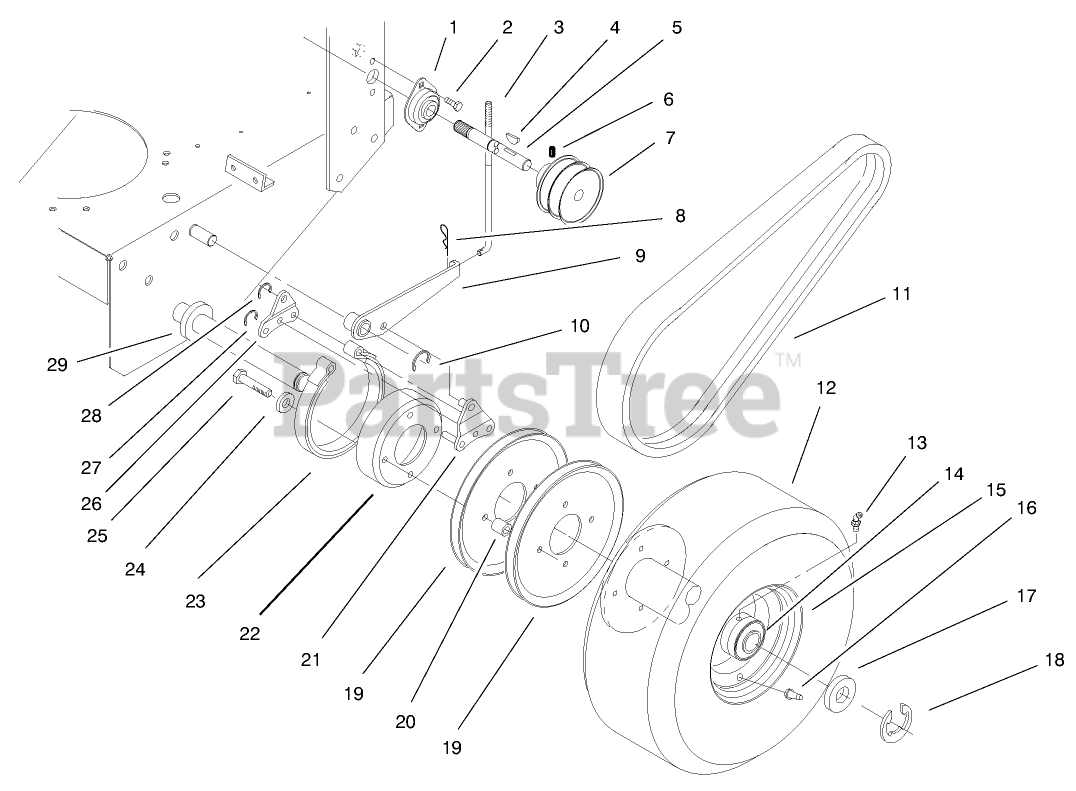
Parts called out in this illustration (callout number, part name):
1	BEARING-EXTERNAL SHAFT
2	SCREW-HH
3	ROD-BRAKE
4	KEY-WOODRUFF
5	SHAFT-EXTENSION, RH
6	SCREW-SET, HS
7	Pulley-Drive
8	PIN-COTTER
9	Brake Arm-LH
10	RING-RETAINING
11	V-BELT
13	FITTING-LUBE, 45 DEG
14	BEARING-BALL
15	WHEEL AND HUB ASM
16	STEM-VALVE
17	WASHER-THRUST
18	RING-RETAINING
19	Pulley-Wheel
20	SPACER-PULLEY
21	LINK-Brake
22	Drum-Brake
23	BAND-BRAKE
24	WASHER-LOCK
25	SCREW-HH
26	Plate-Link
27	RING-RETAINING
28	RING-RETAINING, EXTERNAL
29	WASHER-WHEEL
